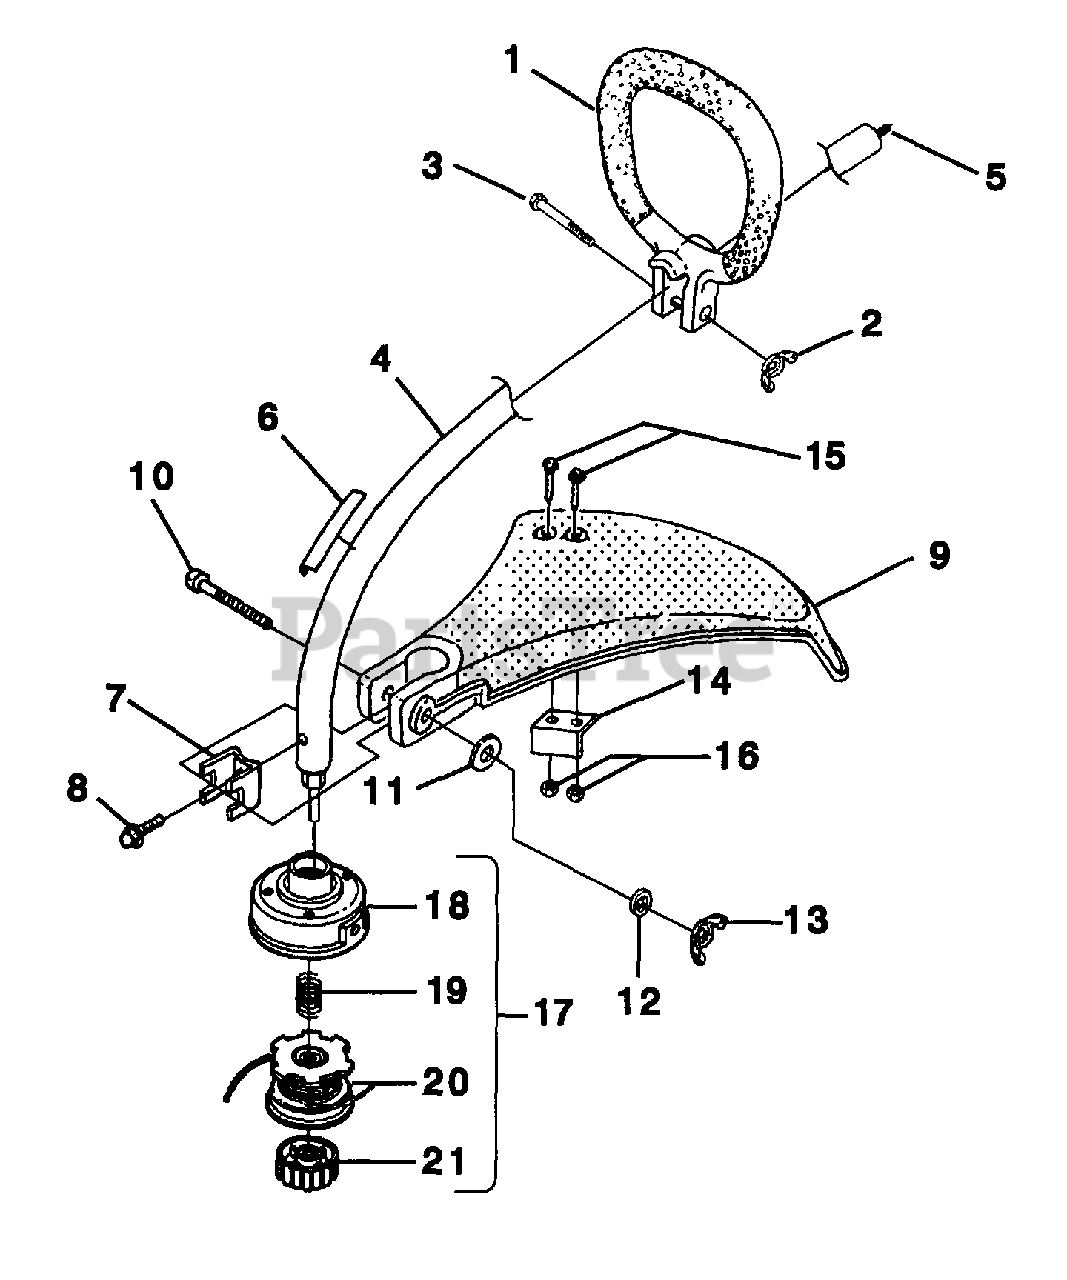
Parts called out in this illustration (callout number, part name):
1	HANDLE ASSY.-Front
2	NUT-Wing, Washer Faced (1/4-20)
3	SCREW-Cap Hex Hd.
4	DRIVESHAFT HOUSING ASSY.
5	SHAFT-Flexible
6	DECAL-Warning
7	CLAMP
8	SCREW-Sems Hex Hd. (#10-24 X 3/8")
9	DEFLECTOR & BLADE KIT (55 Deg.)
10	SCREW-Cap Hex Hd. (10-24 X 2")
11	WASHER-Flat (1/4")
12	WASHER-Lock (1/4")
13	NUT-Wing, Washer Faced (1/4-20)
14	BLADE-Cut-Off
15	SCREW-Mech. Hex Hd. (10-24 X 7/8")
16	NUT-Hex (10-24)
17	STRINGHEAD-Complete
18	HOUSING & EYELET (Dual Line)
19	SPRING-Compression
20	SPOOL & STRING (.080" Line)
21	RETAINER-Spool (R.H. Thread, Black)
